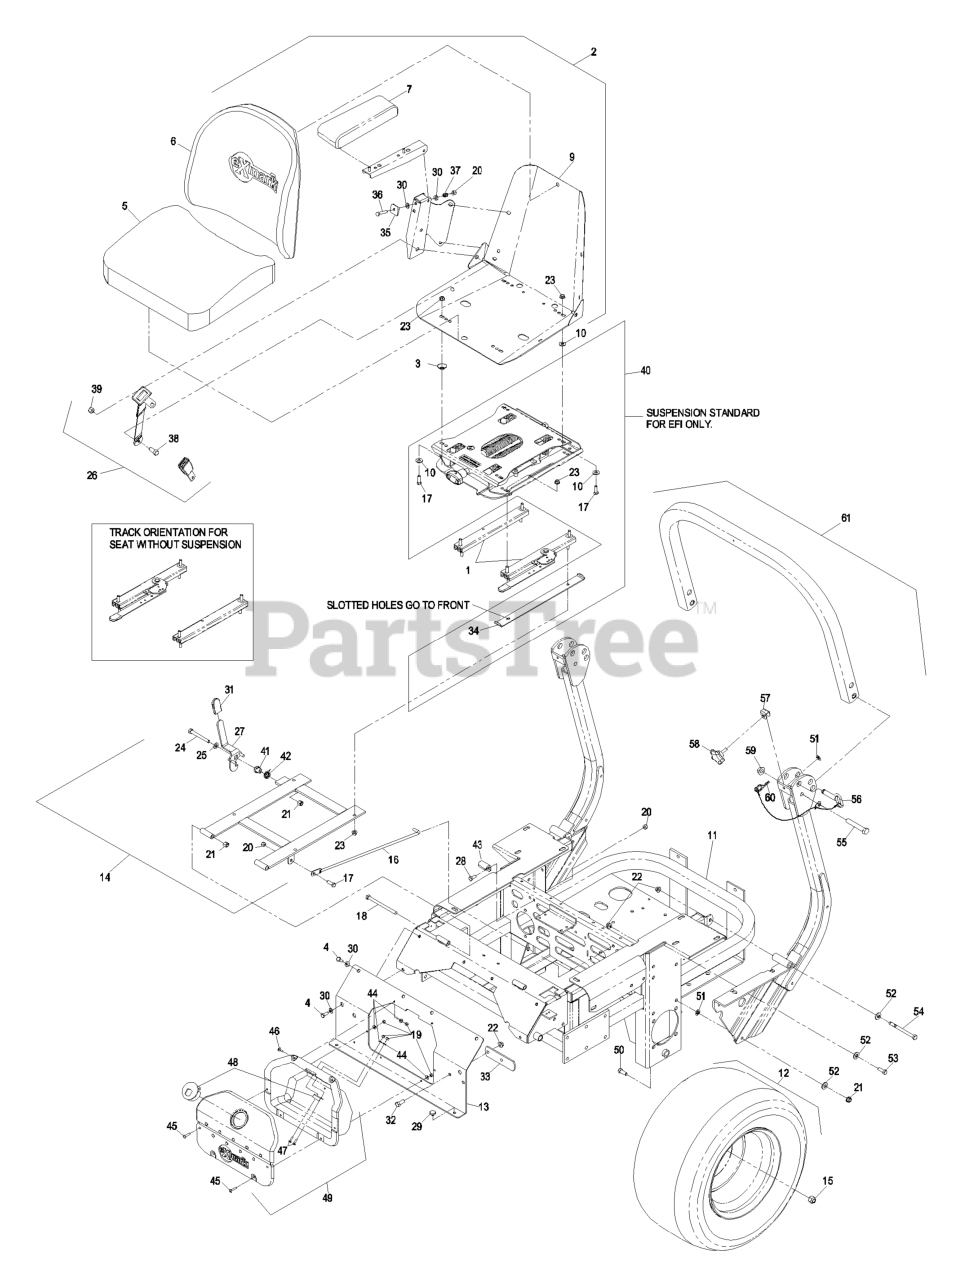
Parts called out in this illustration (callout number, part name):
1	TRACK-SEAT
2	KIT,SEAT W/ARMREST ADJ.
3	SPACER-TRACK
4	SCREW-HH
5	CUSHION,SEAT BOTTOM
6	CUSHION,SEAT BACK
7	CUSHION,ARMREST RH
9	FRAME-SEAT
10	WASHER-FLAT
14	ASM,SEAT FRAME
15	NUT-LUG
16	ROD-HOLDUP, SEAT
17	SCREW-HH
18	SCREW-HH
19	NUT-LOCK, NI
20	NUT-LOCK, NI
21	NUT-LOCK, NI
22	NUT-HHF, WHIZ
24	SCREW-HH
25	WASHER-FLAT
26	SEATBELT KIT
27	LATCH ASM
28	SCREW-HH
30	WASHER-PLAIN
31	GRIP-LEVER
32	SCREW-HH
33	STOP-BRAKE, PARK
34	STOP-SEAT
35	TAB,ARMREST ADJUSTMENT
36	SCREW-HH
37	SPRING-TANK, FUEL
38	SCREW-HH
39	NUT-LOCK, NI
40	KIT,SEAT SUSPENSION
41	BUSHING-LATCH, SEAT
42	SPRING-TORSION
43	CATCH-LATCH, SEAT
44	WASHER-FLAT
46	SCREW-HEAD, TRUSS
47	SCREW-PPH
48	LATCH,CUBBY
49	ASM,CUBBY
50	SCREW-HH
51	NUT-PUSH
52	WASHER-BELLEVILLE
53	SCREW-HH
54	SCREW-HH
55	SCREW-HH
56	PIN-FOLD, ROPS
60	HAIRPIN
61	KIT, LAZER Z 2 POST ROPS
